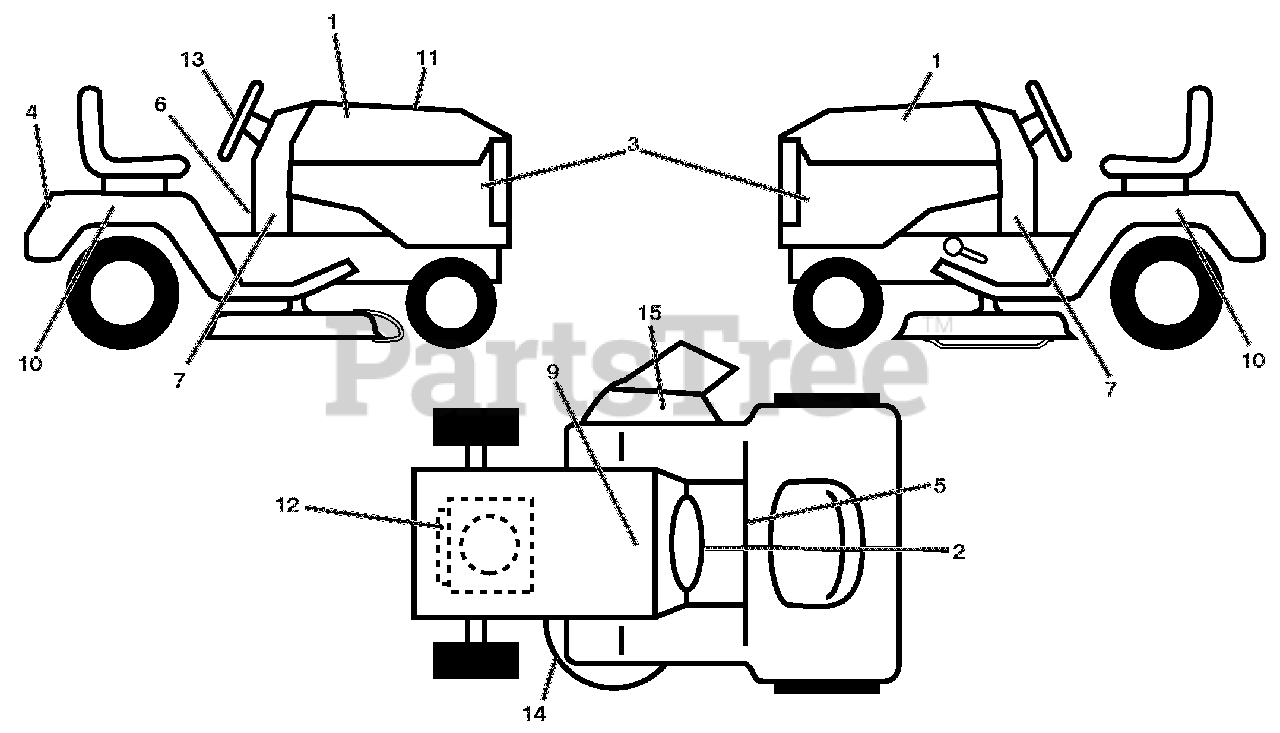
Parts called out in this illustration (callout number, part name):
1	DECAL.HOOD.LH/RH.
2	DECAL, FENDER WARNING
3	DECAL.SDPNL.PWRDBY B&S.ARIENS
4	DECAL.FENDER.REAR.ARIENS
5	DECAL.FENDER
6	DECAL.WARNING SPARK
7	DECAL, DASH.LOWER
9	DECAL.BAT.DAN/POI P/L SYM.WPN
10	DECAL, FENDER SIDES
11	DECAL.REPLACEMENT
12	DECAL, ENGINE
13	DECAL.WHEEL.STEER.ARIENS
14	DECAL.V-BELT.SCH.
15	DECAL DECK/DEFLECT. WARNING
